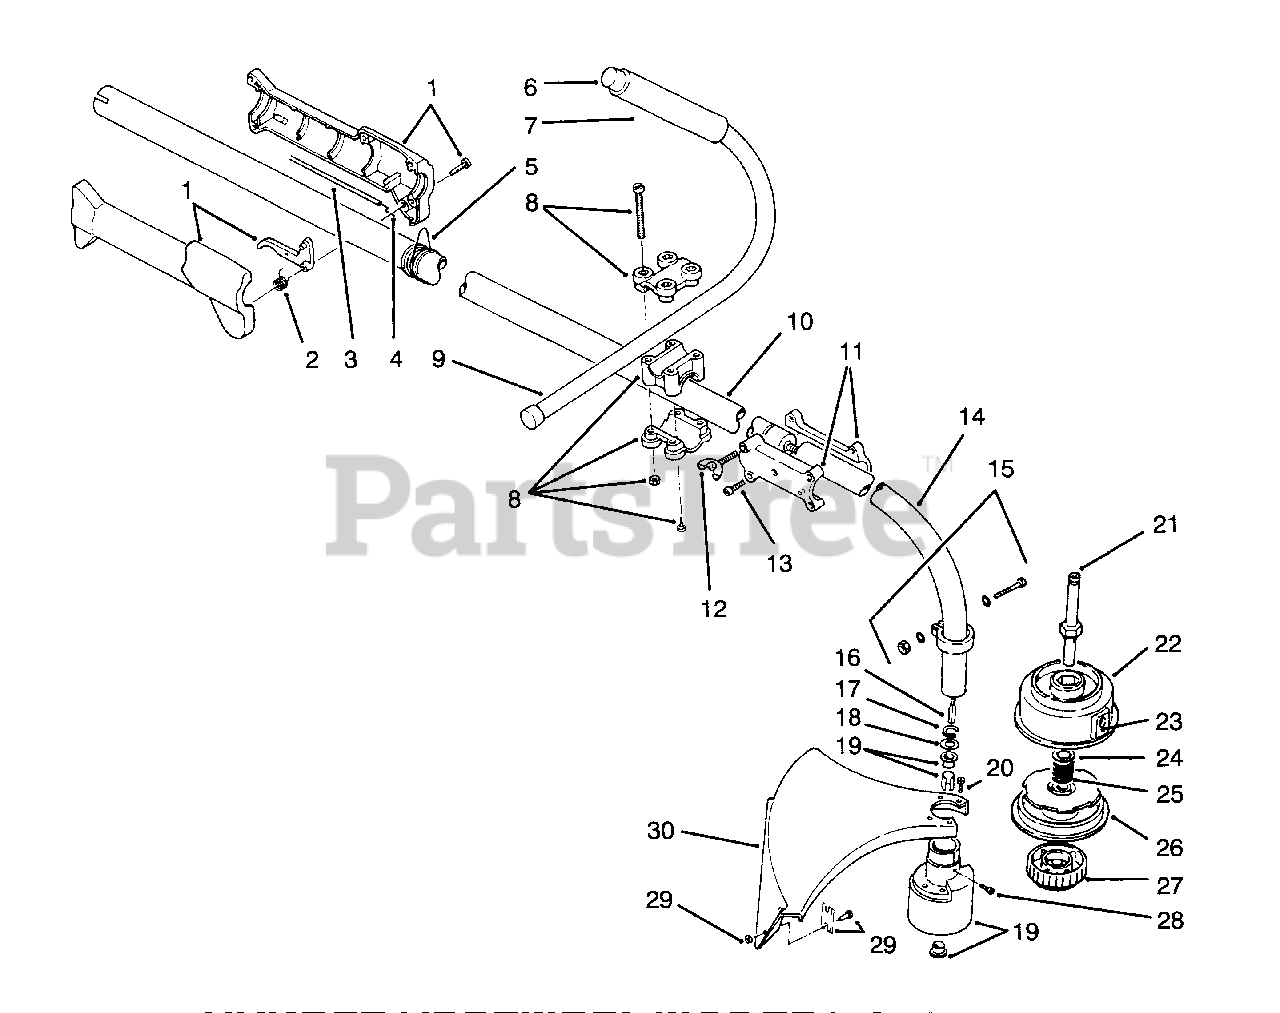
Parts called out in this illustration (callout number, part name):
1	Assy.-Throttle & Trigger (Incl. 6 Screws)
2	Spring-Throttle Trigger
3	Housing-Cable, Throttle
4	Cable-Throttle
5	Clip-Shoulder Strap
6	Closure-Tube
8	Assembly-Bracket Handle (Incl. 4 Screws & Nuts)
9	Assembly-J-Handle (Incl. Ref. No. 6 & 7)
10	Assy.-UpperDrive
11	Coupling-Split Boom
12	Assy.-Adjustment Knob
13	Bolt-Coupling
14	Assy.-Lower Drive Shaft
15	Assy.-Lower Clamp
16	Shaft-Flexible Drive
17	Ring-Retaining
19	Assy.-Bushing Housing
20	Assy.-Guard Mount Screw
21	Shaft-Spool
22	Assy.-Outer Spool & Eyelet
24	Retainer
26	Reel-Inner
27	Assy.-Bump Head
28	Screw-Anit-Rotation
29	Assembly-Blade (Incl. 2 Screws & 2 Nuts)
30	Assy.-Guard & Blade (Incl. Ref. No. 29)
